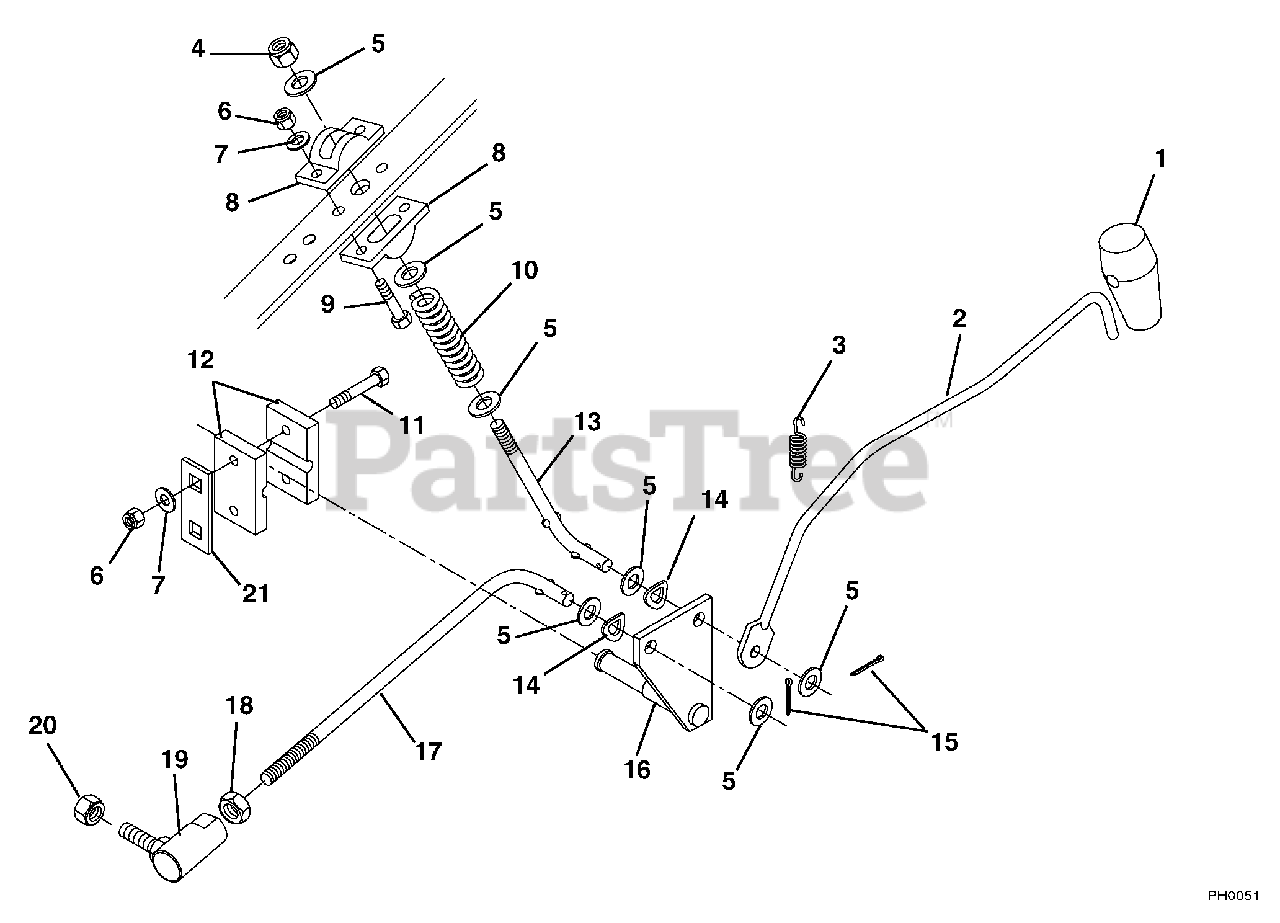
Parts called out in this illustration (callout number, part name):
1	Handle-Rubber Shifter
2	Rod-Shifter
3	Spring-Tension .041 x 1.25 x .50
4	Nut-Locking-Center .375-16 Grade 2
5	Washer-Flat-Steel .406 x .812 x .065
6	Nut-Locking-Center .250-20 Grade 2
7	Washer-Flat-Steel .281 x .620 x .065
8	Cam-Shifter
9	Bolt-Hex .25-20 x 1.00 Grade 5
10	Spring-Compression .081 x .720 x 2.75
11	Bolt-Hex .25-20 x 1.50 Grade 5
12	Block-Shift Lever
13	Link-Shifter Stop
14	Spring Washer
15	Pin-Cotter .12 x .75
16	Weldment, PTO Bellcrank
18	Nut-Hex .375-24 Grade 2
19	Ball Joint
20	Nut-Locking Nylon .375-24 with Insert
21	Shim-Mower Height Adjuster Bracket
